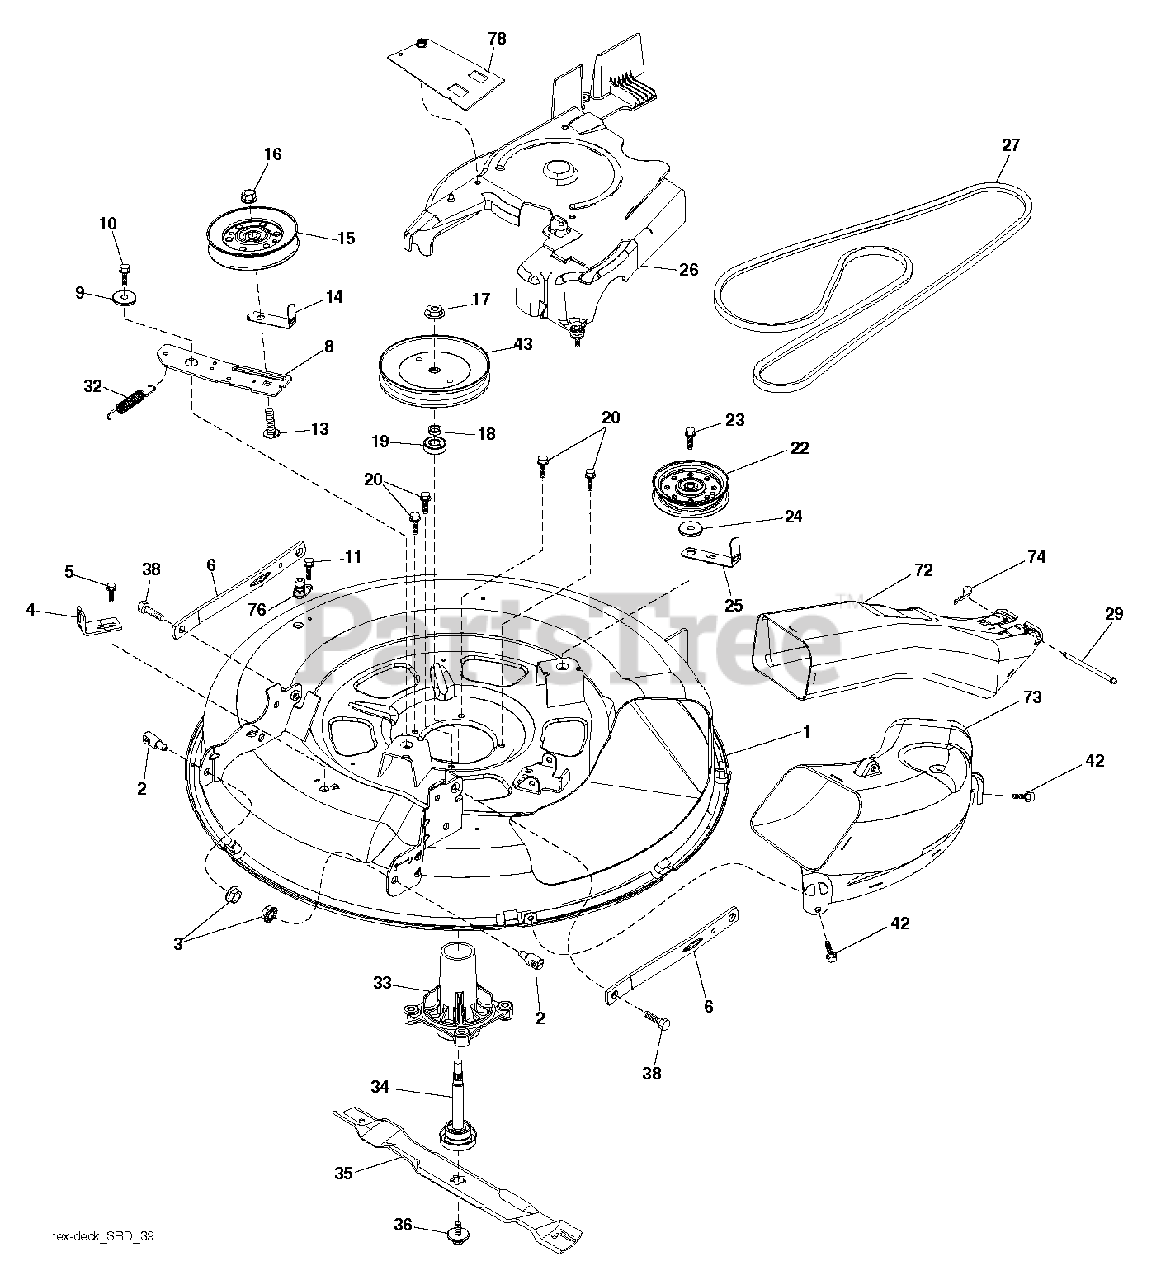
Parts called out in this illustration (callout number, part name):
2	STUD.FASTNER.W/ANTI-ROTATE
3	NUT LOCK HEX FLANGE 5/16-18
5	BOLT.5/16HEX.WHS.HD
6	ARMS.SUSP.MOWER.REAR.SRD
9	SPACER.RETAINER
10	SCREW 3/8-16X1
11	SCREW.1/4-20X5/8
13	BOLT.3/8-16X1.50
14	KEEPER, BELT IDLER
15	PULLEY.IDLER.4.25
16	NUT LOCK FLG 3/8-16 UNC
17	NUT.FLANGE.LOCK.TOP
18	WASHER.SPACER.MANDREL
20	SCREW, WASHER HEAD
22	PULLEY.IDLER.FLAT.46.PR.DR.
23	SCREW LT
27	V-BELT.DRIVE.MOWER.30"
32	SPRING.MOWER.DRIVE.ELECTRIC
33	HOUSING MANDREL
34	SHAFT.ASM.MDRL.N/GREASE.38
35	BLADE.MOWER.BAGGING.30"
36	BOLT.WASHER.ASM.7/16-2
38	BOLT.SHOULDER
42	SCREW, 3/8-16X3/4
43	PULLEY, MANDREL 6.5 PD
74	RETAINER-SPRNG RB
76	PORT.WASHOUT
